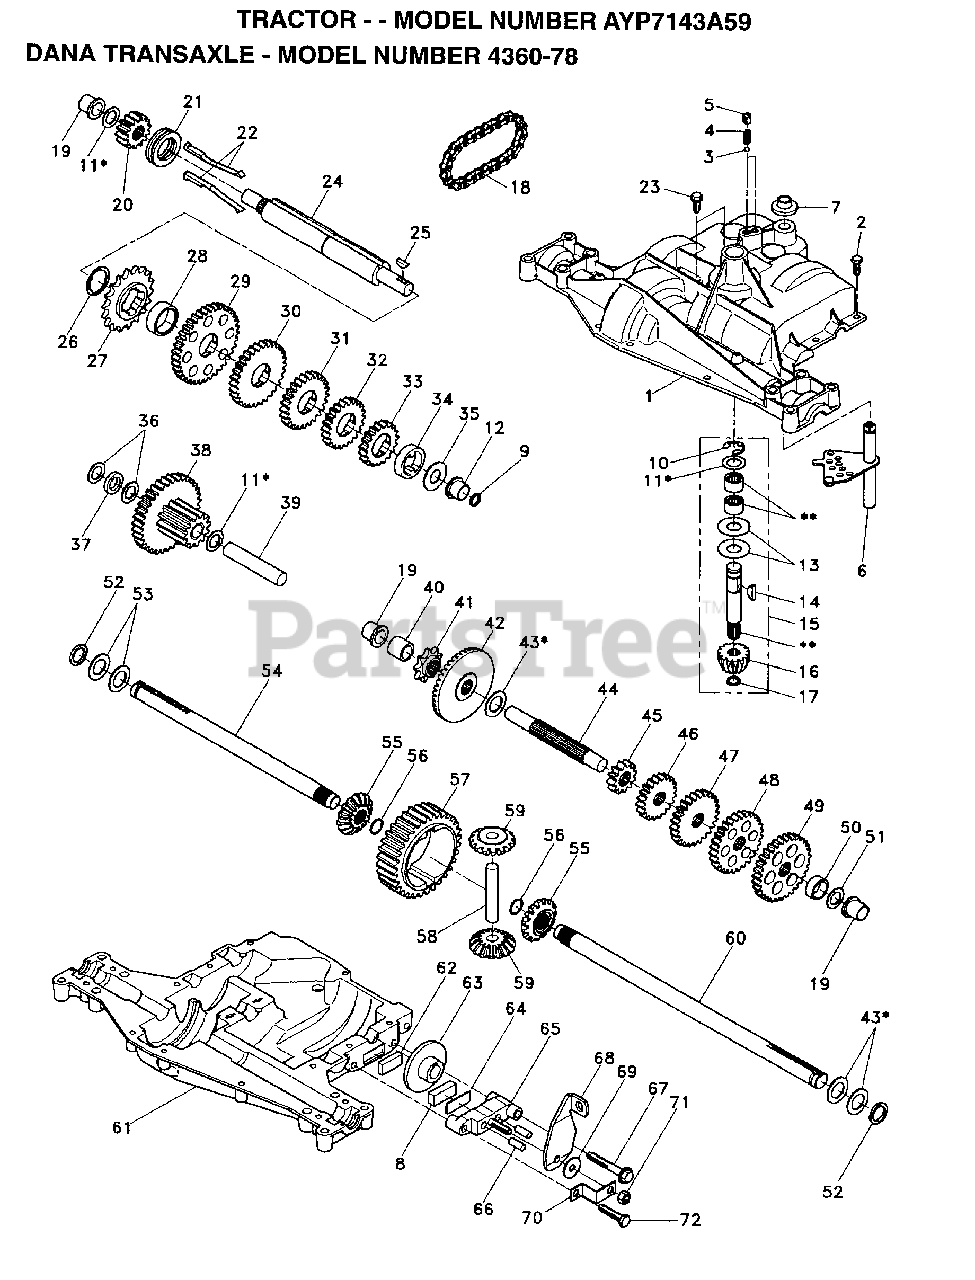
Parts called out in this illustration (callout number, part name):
1	HOUSING, UPPER
3	BALL, DETENT
4	SPRING, DETENT
5	SCREW, SET
6	SHIFTER ASSEMBLY
7	BOOT, SHIFTER
8	PUCK, FRICTION
10	RING, RETAINING
11	ASSY, KIT, SHIM .625 SHAFT
12	BEARING, FLANGE
13	WASHER, PLAIN .632 X 1.38 X .046
14	KEY, WOODRUFF, #9
15	ASSEMBLY, KIT, INPUT SHAFT
16	PINION, BEVEL, 14 TEETH
17	RING, RETAINING
18	CHAIN, 24 PITCHES
19	BEARING, FLANGE
20	GEAR, SPUR, 14 TEETH
21	COLLAR, CLUTCH
22	ASSEMBLY, KIT, CLUTCH KEYS
23	SCREW TAPPING WITH SEALER
24	SHAFT, INTERMEDIATE
25	KEY, WOODRUFF, #61
26	RING, RETAINING
27	SPROCKET, 18 TEETH
29	GEAR, SPUR, 37 TEETH
30	GEAR, SPUR, 30 TEETH
31	GEAR, SPUR, 25 TEETH
32	GEAR, SPUR, 22 TEETH
33	GEAR, SPUR, 19 TEETH
35	WASHER, PLAIN .640 X 1.37 X .061
36	WASHER, PLAIN .632 X 1.00 X .026
37	SPACER .630 X 1.00 X .169
38	ASSY GEAR COMB 12&35 TEETH
39	SHAFT, IDLER
40	SPACER .635 X .875 X .755
41	SPROCKET, 9 TEETH
42	GEAR, BEVEL, 42 TEETH
43	ASSY, KIT, SHIM .750 SHAFT
44	SHAFT, DRIVE
45	GEAR SPUR, 12 TEETH
46	GEAR, SPUR, 20 TEETH
47	GEAR, SPUR, 25 TEETH
48	GEAR, SPUR, 28 TEETH
49	GEAR, SPUR, 31 TEETH
51	WASHER, PLAIN .632 X 1.00 X .060
52	WASHER, NEOPRENE
53	WASHER, PLAIN .758 X 1.25 X .031
54	AXLE LEFT HAND
55	GEAR, MITER, 15 TEETH
56	RING, RETAINING
57	GEAR, SPUR, 32 TEETH
58	SHAFT, CROSS
59	GEAR, MITER, 15 TEETH
60	AXLE, R.H.
61	HOUSING, LOWER
62	PUCK, FRICTION
63	DISC, BRAKE
65	JAW, BRAKE
66	PIN, DOWEL
67	SCREW, SELF-TAPPING
68	LEVER ACTUATING
69	WASHER, PLAIN .321 X 1.00 X .055
70	BRACKET, ANTI-ROTATION
71	LOCKNUT 5/16-24
72	SCREW TAPPING
